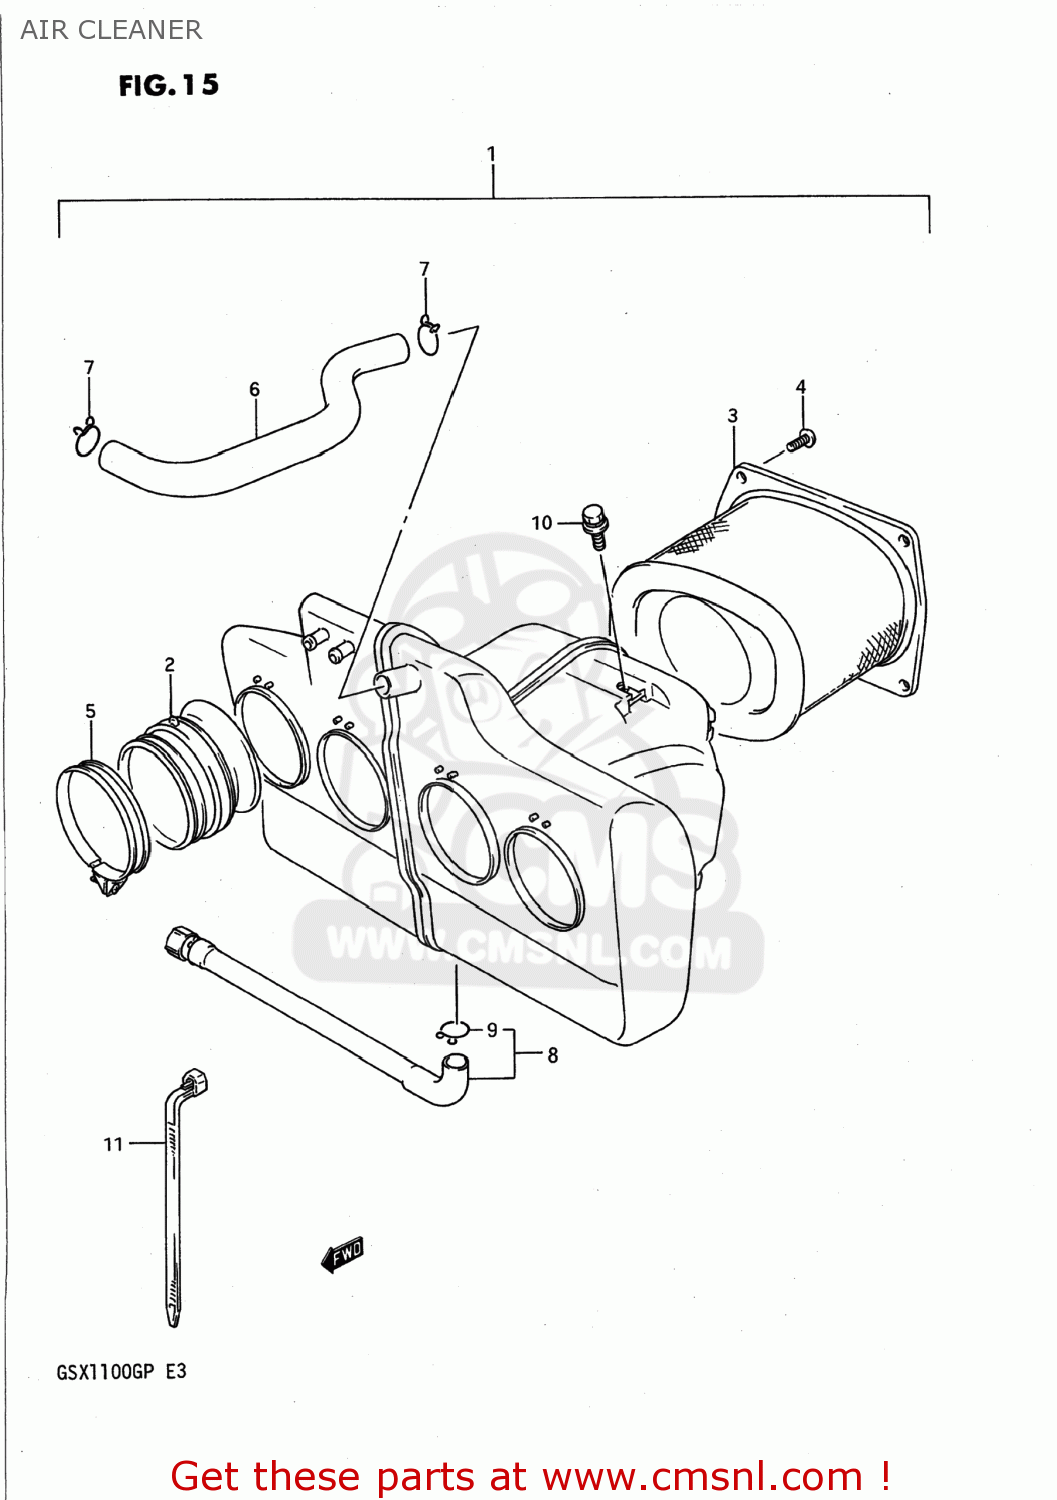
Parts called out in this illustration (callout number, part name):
1	CLEANER ASSEMBLY,AIR
2	TUBE,OUTLET
3	FILTER ASSY
4	SCREW, FRONT & REAR
5	CLAMP
6	TUBE,BREATHER
7	CLIP
8	DRAIN TUBE
9	CLIP
10	BOLT
11	CLAMP(L:125)
